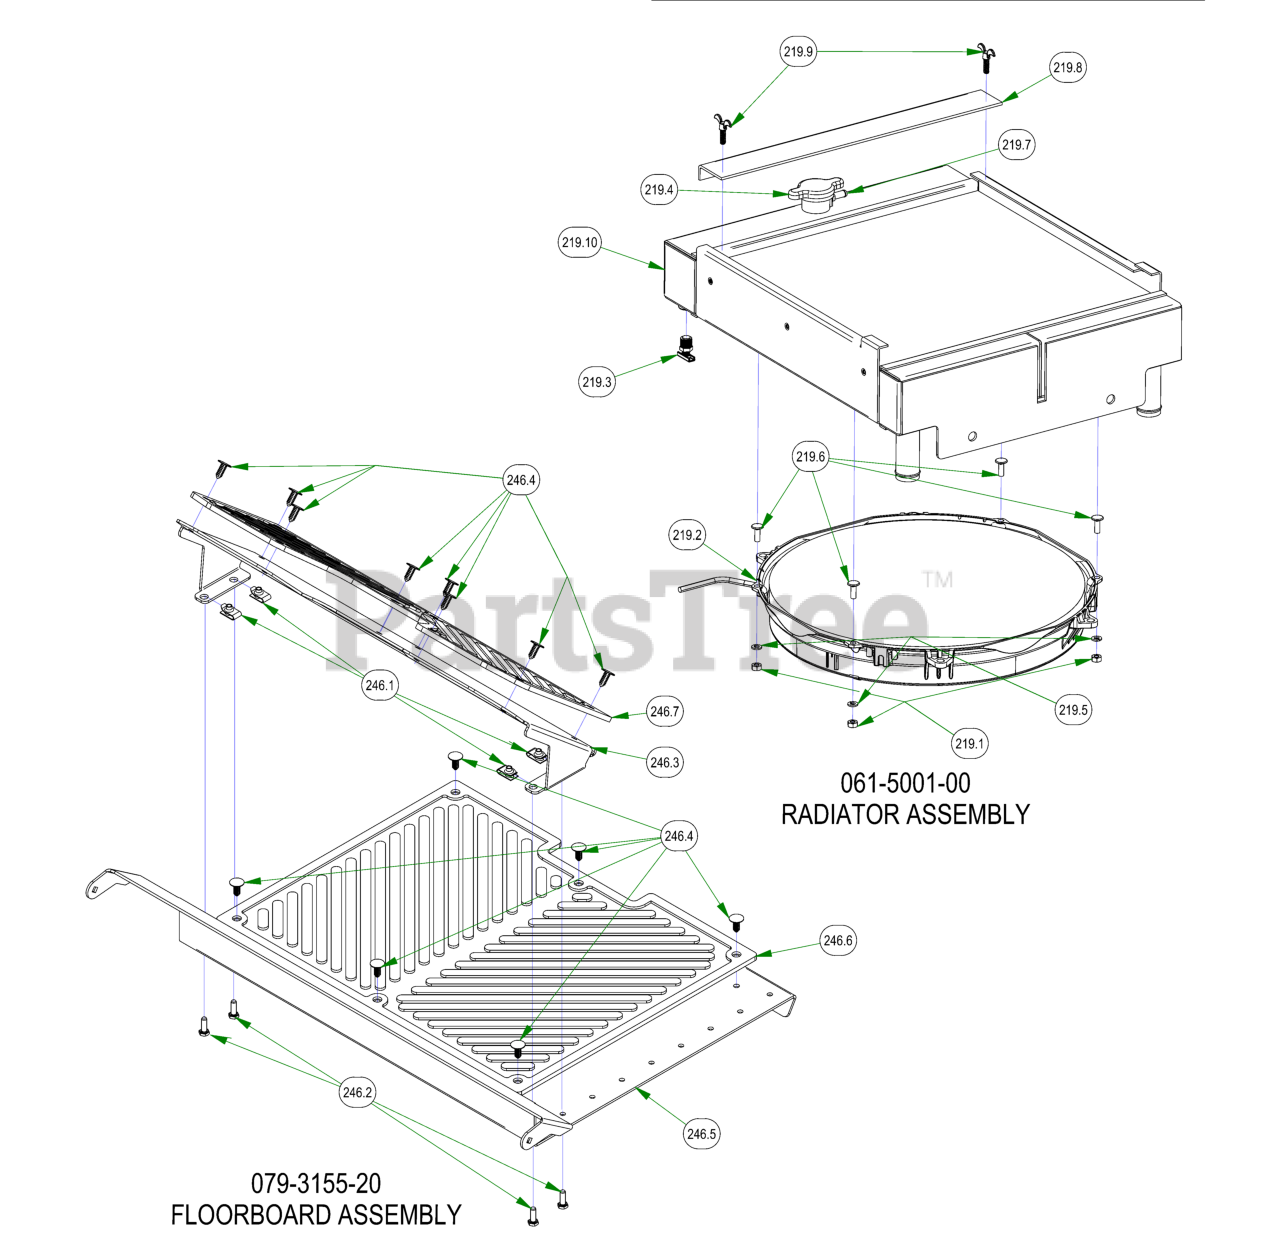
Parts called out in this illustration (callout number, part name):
219	2019 Diesel Radiator Kit
219.1	1/4-20 Hex Nut
219.2	Electric Fan for 2019 Diesel Radiator
219.3	1/4 NPT Drain Plug
219.4	radiator cap
219.5	1/4" Lock Washer
219.6	1/4" x 3/4" Carriage Bolt
219.7	1/4 Barb to 3/16 NPT Overflow Fitting
219.8	Screen Rentention Plate for 2019 Diesel Radiator
219.9	1/4-20 x 3/4 Thumb Screw
219.10	2019 Diesel Radiator
246	R-Series Floorboard Assembly
246.1	1/4-20 Cage Nut
246.2	1/4-20 X 3/4 HEX CAP SCREW (GR.5) ZINC
246.3	OUTLAW ADJUSTABLE FOOT PLATE-ORANGE
246.4	Ratchet Fastener
246.5	2019 Outlaw Floorboard
246.6	MAT (FLOOR)
246.7	MAT (FOOT PLATE)
